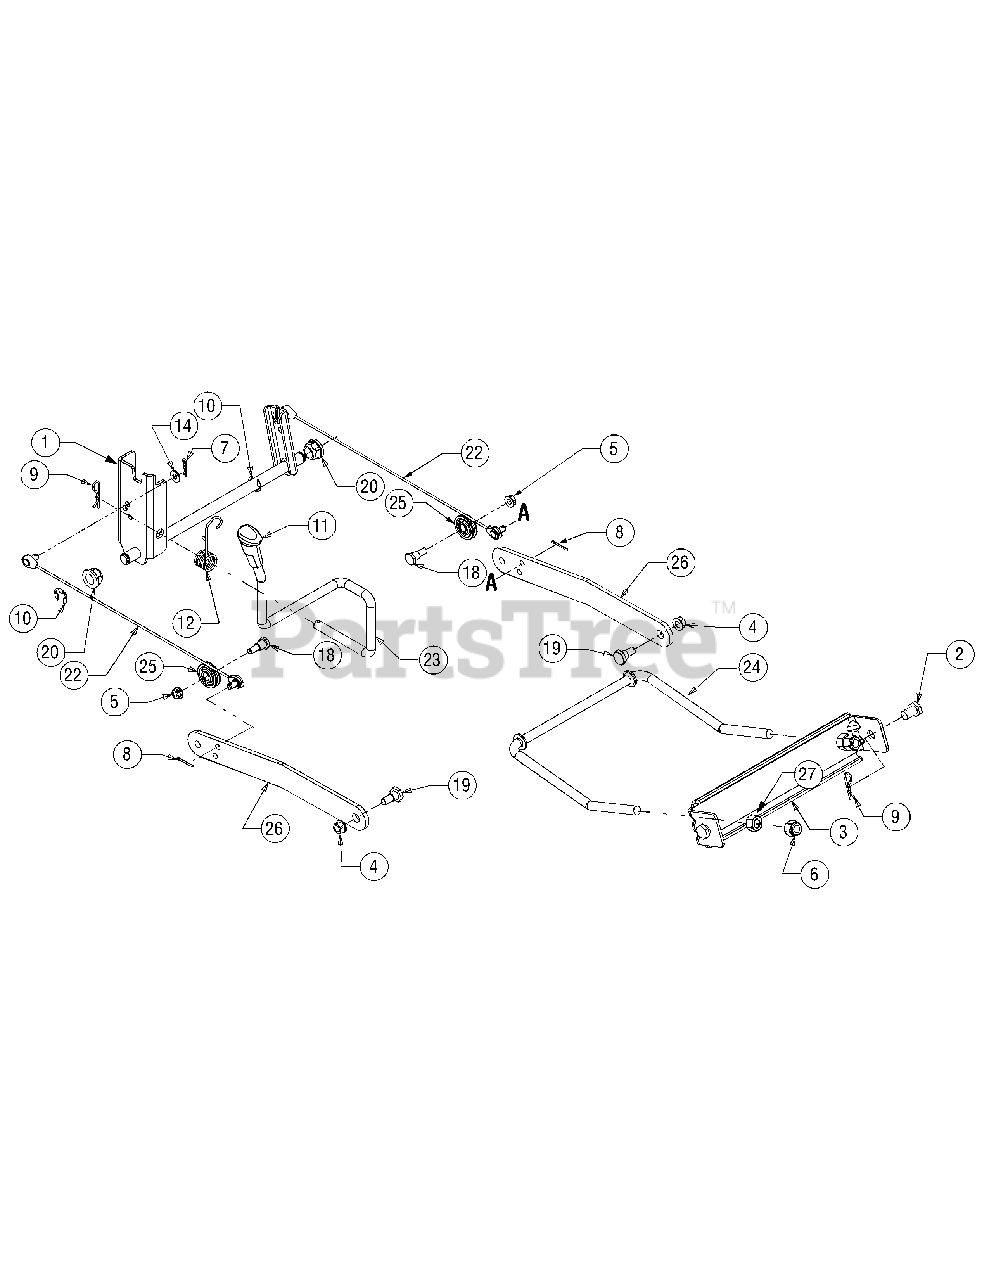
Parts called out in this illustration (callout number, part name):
4	Nut, Nylon Lock, 3/8-16
5	Nut, Nylon Lock, 5/16-18, Gr5
6	Nut, Hex Lock, 1/2-13, Gr8, Nylon
7	Pin, Cotter, .072 Dia. x 1.13 Lg
8	Pin, Cotter, 3/32, 1.0
9	Pin, Click, .092 x 1.64 Lg
10	E-ring, .625 Dia. Shaft
11	Grip, Handle
12	Spring, Torsion
18	Screw, Hex Cap, 5/16-18x.620 Gr2
19	Shoulder Screw, 3/8-16
20	Bearing, Hex Flange
22	Cable, Lift, 16.16 Lg
23	Handle, Lift
24	Rod, Deck .5" Dia.
25	Pulley, Roller
27	Nut, Hex, 1/2-13
